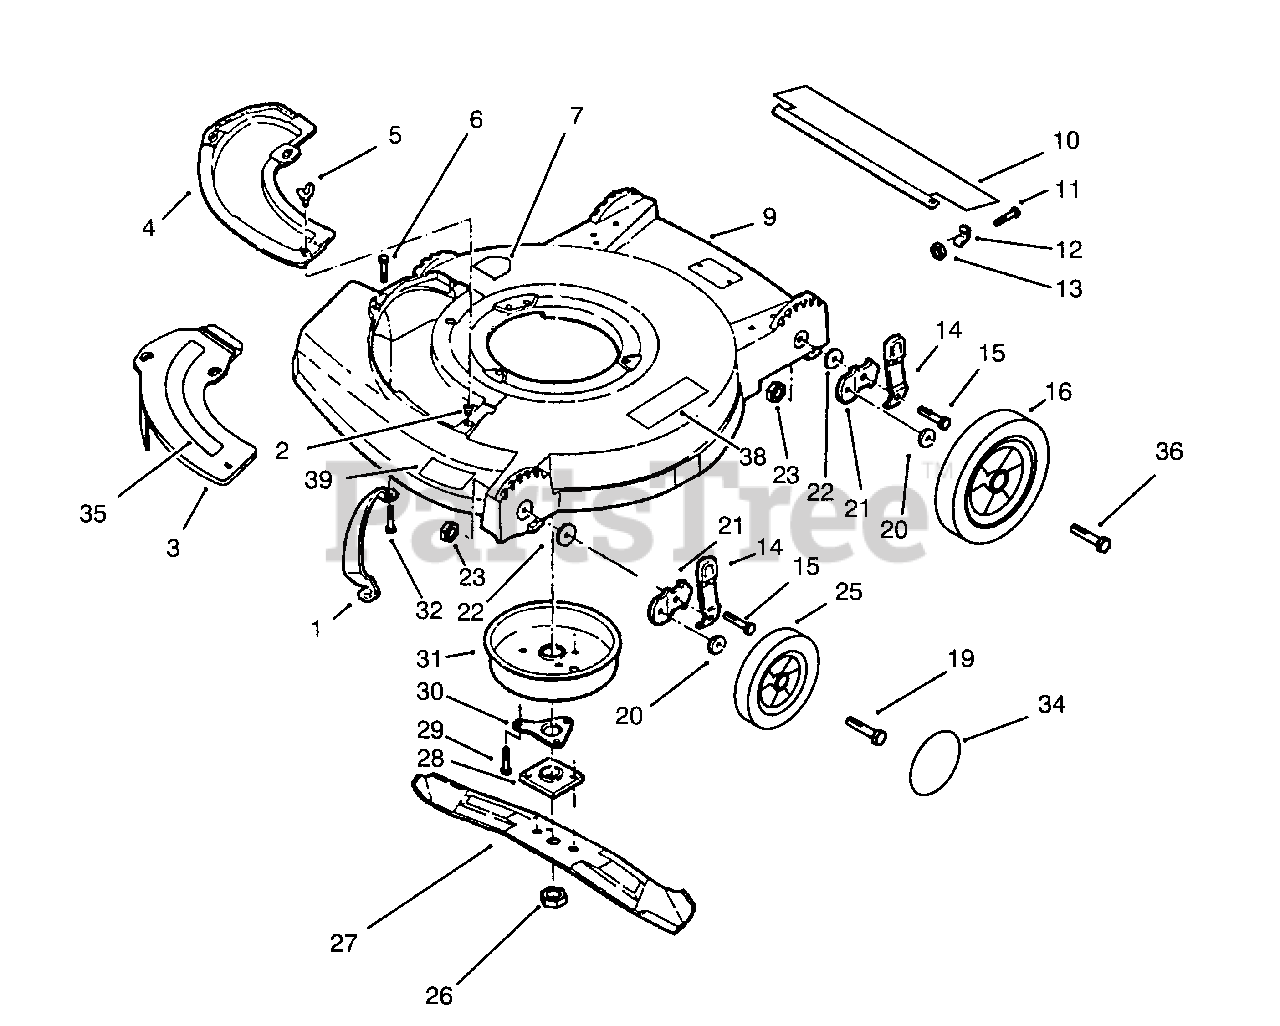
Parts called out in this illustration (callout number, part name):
1	Toe Bar
2	Grommet
3	Cover-Plate, Mulch (Incl. Ref.#35)
4	Cover Plate
5	Nut-Wing
6	Screw-Plate Mounting
7	Decal-Danger (Engish)
9	Housing Assembly (Incl. Ref. # 2, 7,38 & 39)
10	Shield-Trailing
11	Screw-Trailing Shield
14	Knob and Spring Assembly
15	Bolt-Shoulder
16	Wheel-Rear 8"
19	Bolt-Wheel 6"
21	Bracket-Wheel Ht. Adjust
22	Washer-Wheel Ht. Adjust
23	Nut-Wheel Ht. Adjust
25	Wheel-Front 6"
26	Nut
27	Blade 19"
28	Collar and Plate Assembly
29	Screw-Muff. to Muff. Plate
30	Support-Crankshaft
31	Muffler Cover Assembly
36	Bolt-Wheel 8"
38	Decal-Warning
39	Decal-No Rust
